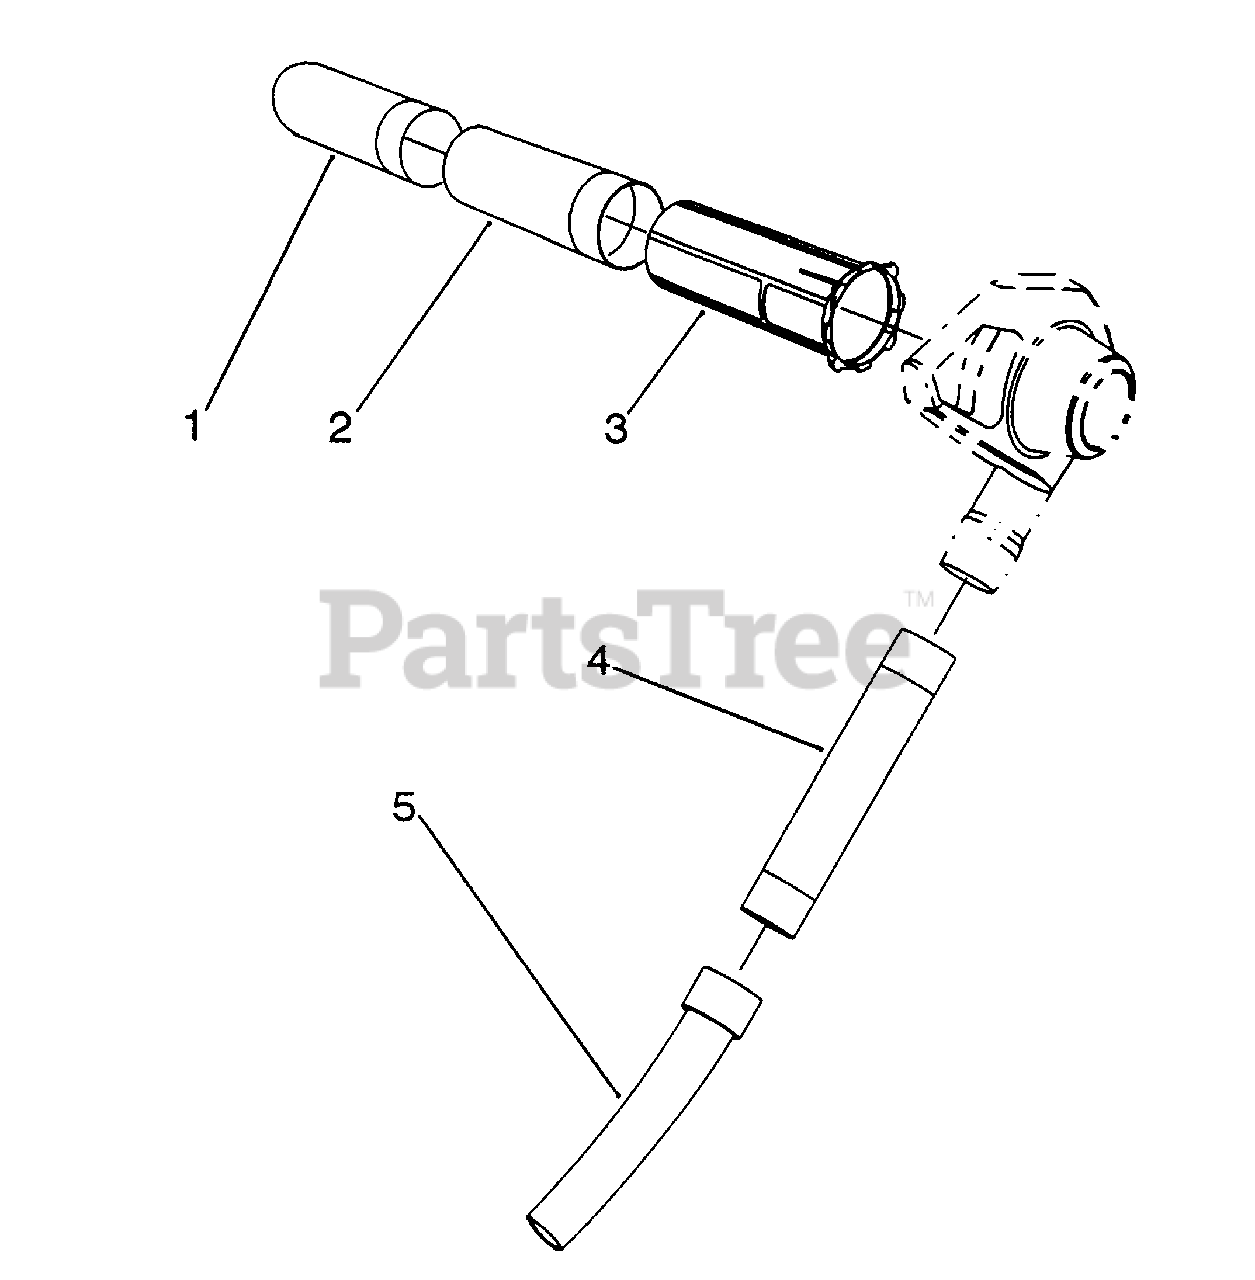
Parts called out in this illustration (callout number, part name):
1	Vac Tube-Lower
2	Vac Tube-Middle
3	Vac Tube-Upper
4	Tube-Blower
